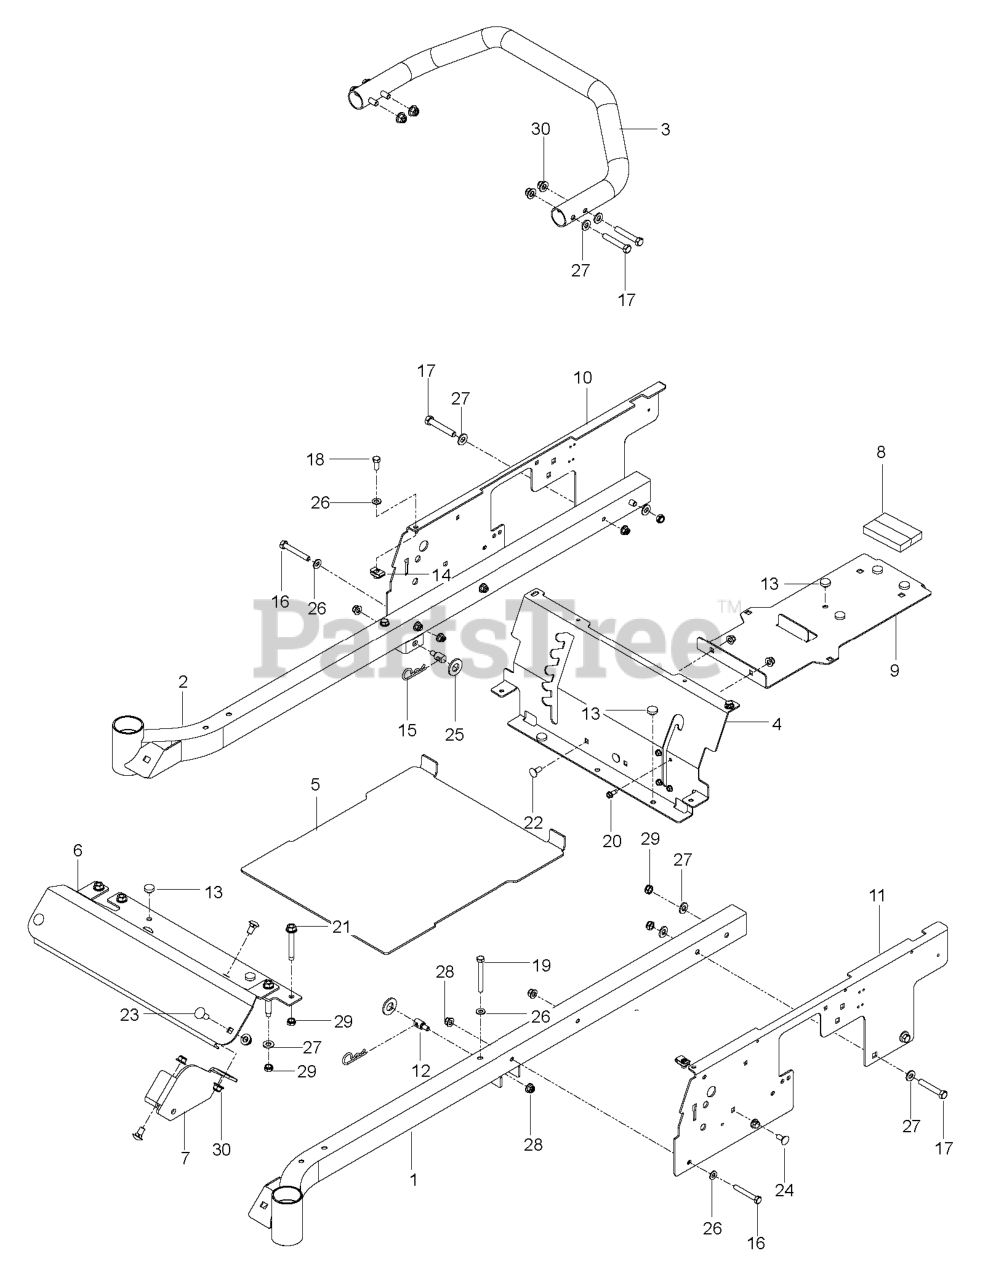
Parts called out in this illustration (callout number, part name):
1	FRAME TUBE, LH, ORG
2	FRAME TUBE, RH, ORG
3	IMPACT BAR, ORG
4	PANEL, SEAT SUPP. ORG
5	PLATE, FOOT W/DECALS, HUSQ
6	FOOT.REST.30/38.ORANGE
7	BRACKET, FRONT DECK, BLK
8	FOAM STRIP, FUEL TANK
9	SUPPORT, TANK/BATT, BLK
10	PLATE.RH.SIDE.ORANGE
11	PLATE.LH.SIDE.ORANGE
12	STUD.FASTNER.W/ANTI-ROTATE
13	GROMMET, BUMPER
14	U-CLIP 5/16-18 NUT RETAINER
15	HAIRPIN #4
16	BOLT.FIN HEX 5/16-18UNC X2 1/4
17	BOLT.HEX
18	BOLT.FIN.HEX.5/16-18X3/4
20	SCREW 1/4 X 5/8
21	HHFS 3/8-16 X 2-3/4 GR5 ZD
22	RP BOLT 5/16-18 X3/4 ZN/YEL GR
23	BOLT D
24	Bolt - Rd. Hd. Sq. Neckiage 3/8 16 x 3/4
25	WASHER
26	FLAT WASHER 5/16 SAE
27	WASHER
28	WASHER 5/8 FLAT
28	5/16-18 NYLOC FLANGE NUT
29	NUT HEX 3/8-16 NYLON, THIN
30	NUT 3/8-16 HEX FLG NYLOC ZD
